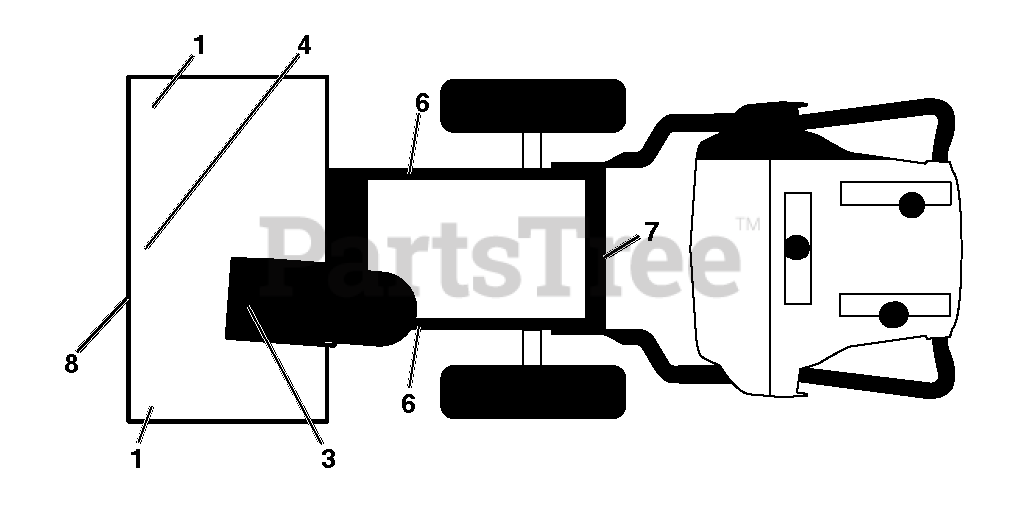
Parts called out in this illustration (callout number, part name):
1	DECAL.AUGER.SAFETY.
3	DECAL.CHUTE.SAFETY.EU/SC.17
4	DECAL.AUGER."
6	DECAL.BELT.GUARD.
7	DECAL.NOISE.LEV.105/CE.EAC.UKR
8	DECAL.AUGER HSG.HUSQ.ST 224
